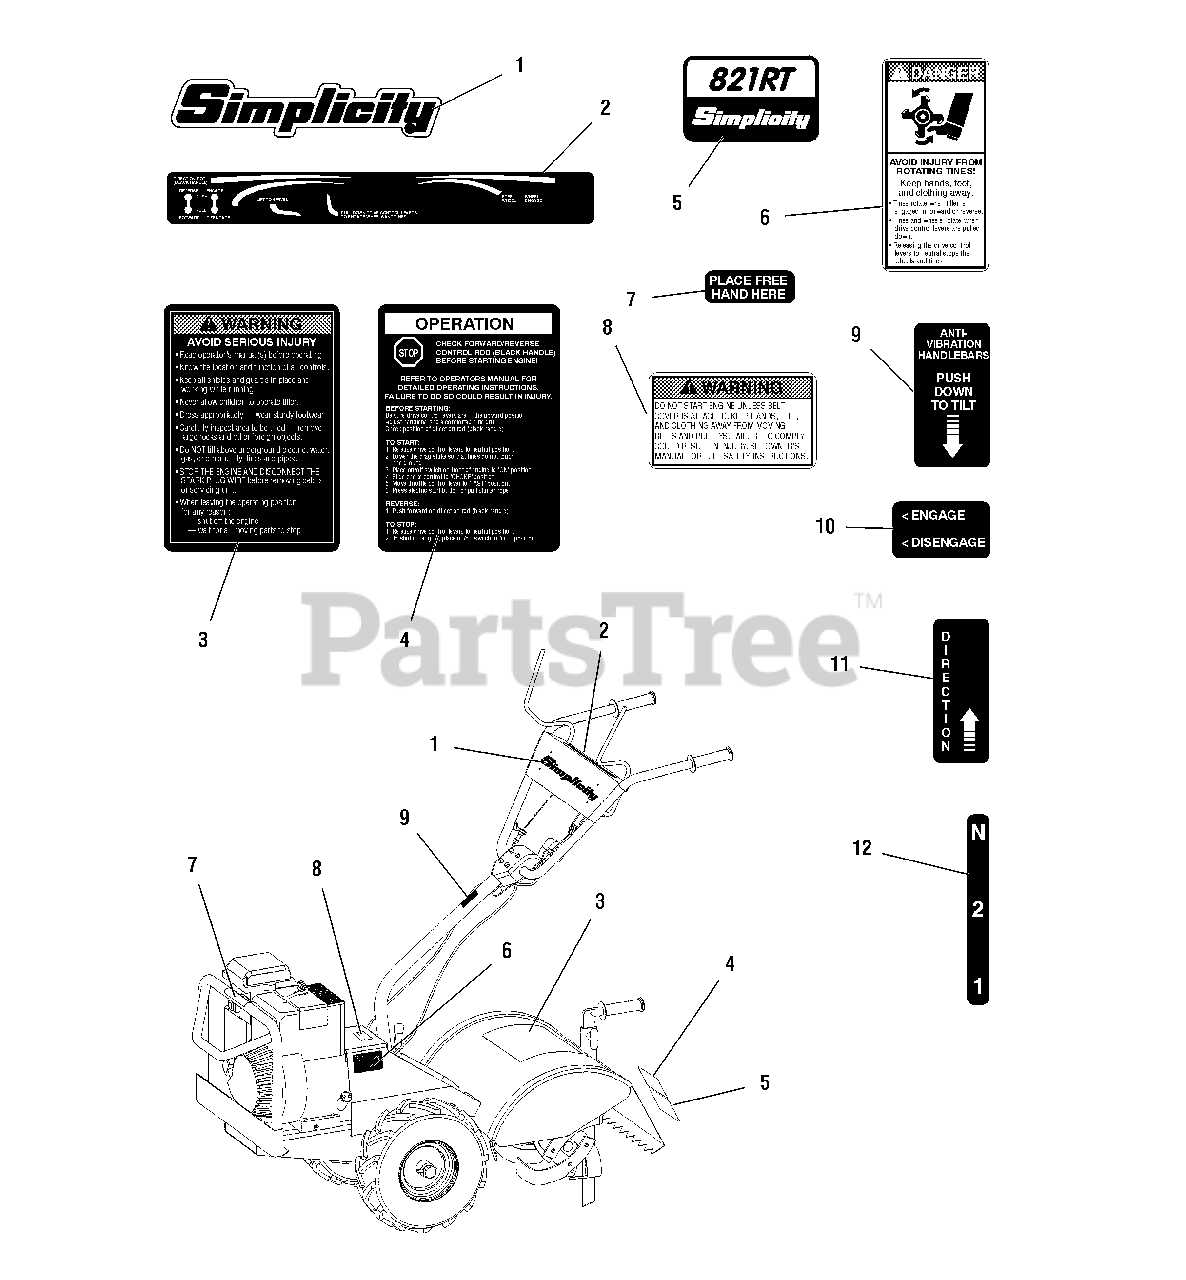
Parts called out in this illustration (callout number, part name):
1	DECAL, Simplicity
2	DECAL. Console
3	DECAL, Hood
4	DECAL, Hood
5	DECAL, Model 821RT
6	DECAL, Tine Hood
7	DECAL, Brush Bar
8	DECAL, Belt Cover
9	DECAL, Handle Bar
10	DECAL, Trans. Cover
11	DECAL, Trans. Cover
12	DECAL, Handlebar Base
